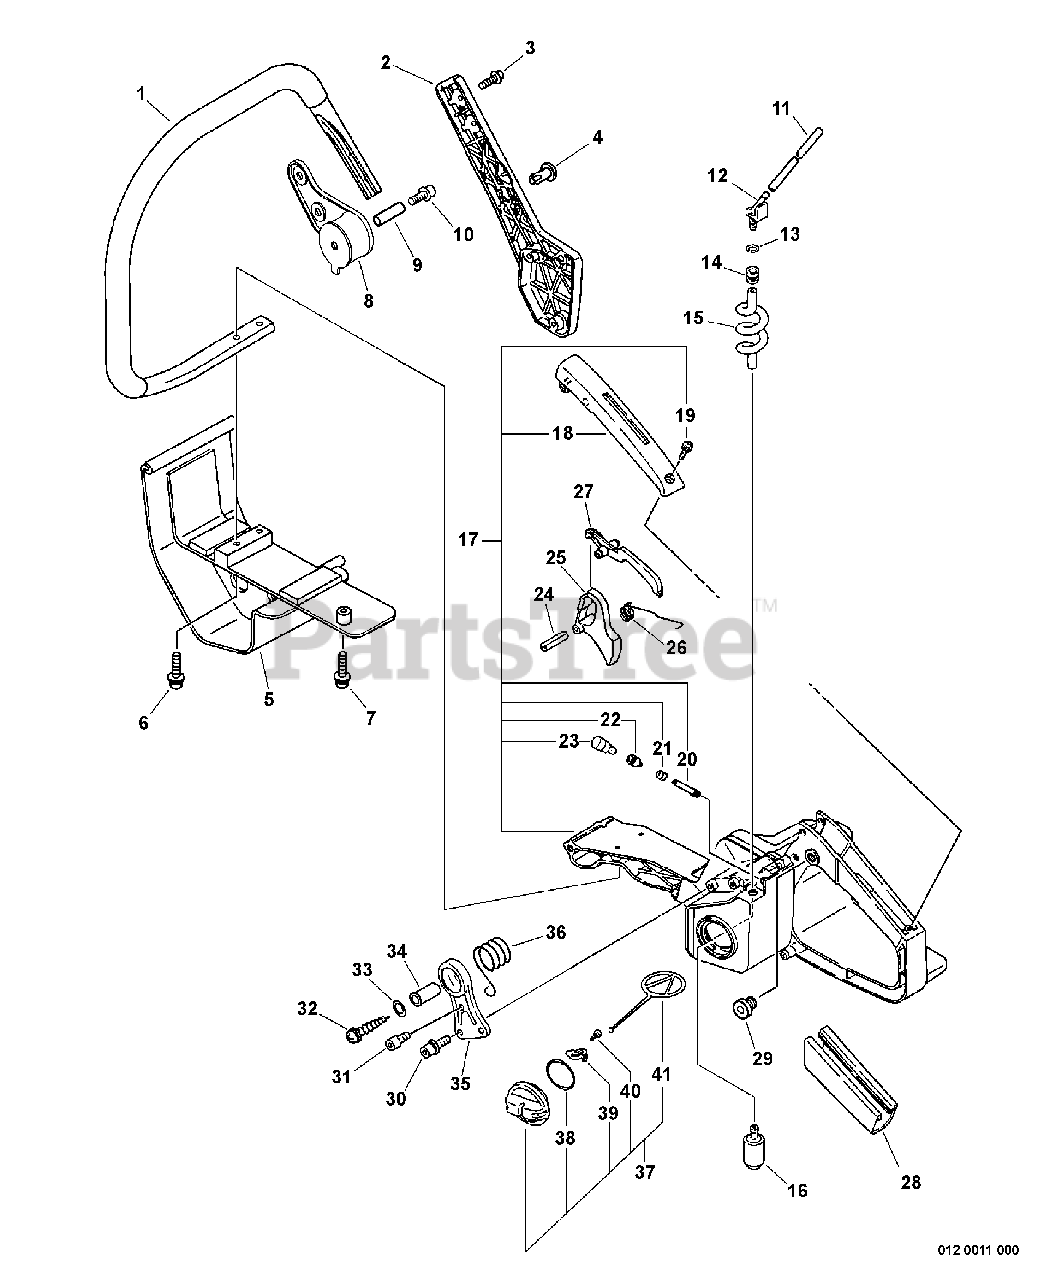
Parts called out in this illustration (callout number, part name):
1	HANDLE, FRONT
2	BRACKET, HANDLE
3	SCREW 5×20
6	BOLT 5×30
7	BOLT 5×25
8	CUSHION 5
9	COLLAR 5
10	BOLT 5×20
11	PIPE, FUEL 3×6×110
12	CONNECTOR, PIPE
13	CLIP Ø6.5 MM
14	GROMMET
15	PIPE, FUEL
16	FILTER, FUEL
17	HANDLE ASSY, REAR
18	COVER, HANDLE
19	SCREW 4×14
20	PIPE, VENT
22	HOLDER, VENT
23	VENT ASSY
24	PIN, SPRING Ø5×25 MM
25	TRIGGER, THROTTLE
26	SPRING, THROTTLE RETURN
27	LEVER, THROTTLE LOCKOUT
28	GRIP, HANDLE
30	BOLT 5×14
31	BOLT 5×8
32	SCREW - 5×35
33	WASHER 5
34	COLLAR 5
35	BRACKET, CUSHION
36	SPRING, COMPRESSION
37	CAP ASSY, FUEL
38	O-RING 29
39	RETAINER, CONNECTOR
40	SCREW, TAPPING 3×8
41	CONNECTOR, CAP L= 60 MM
